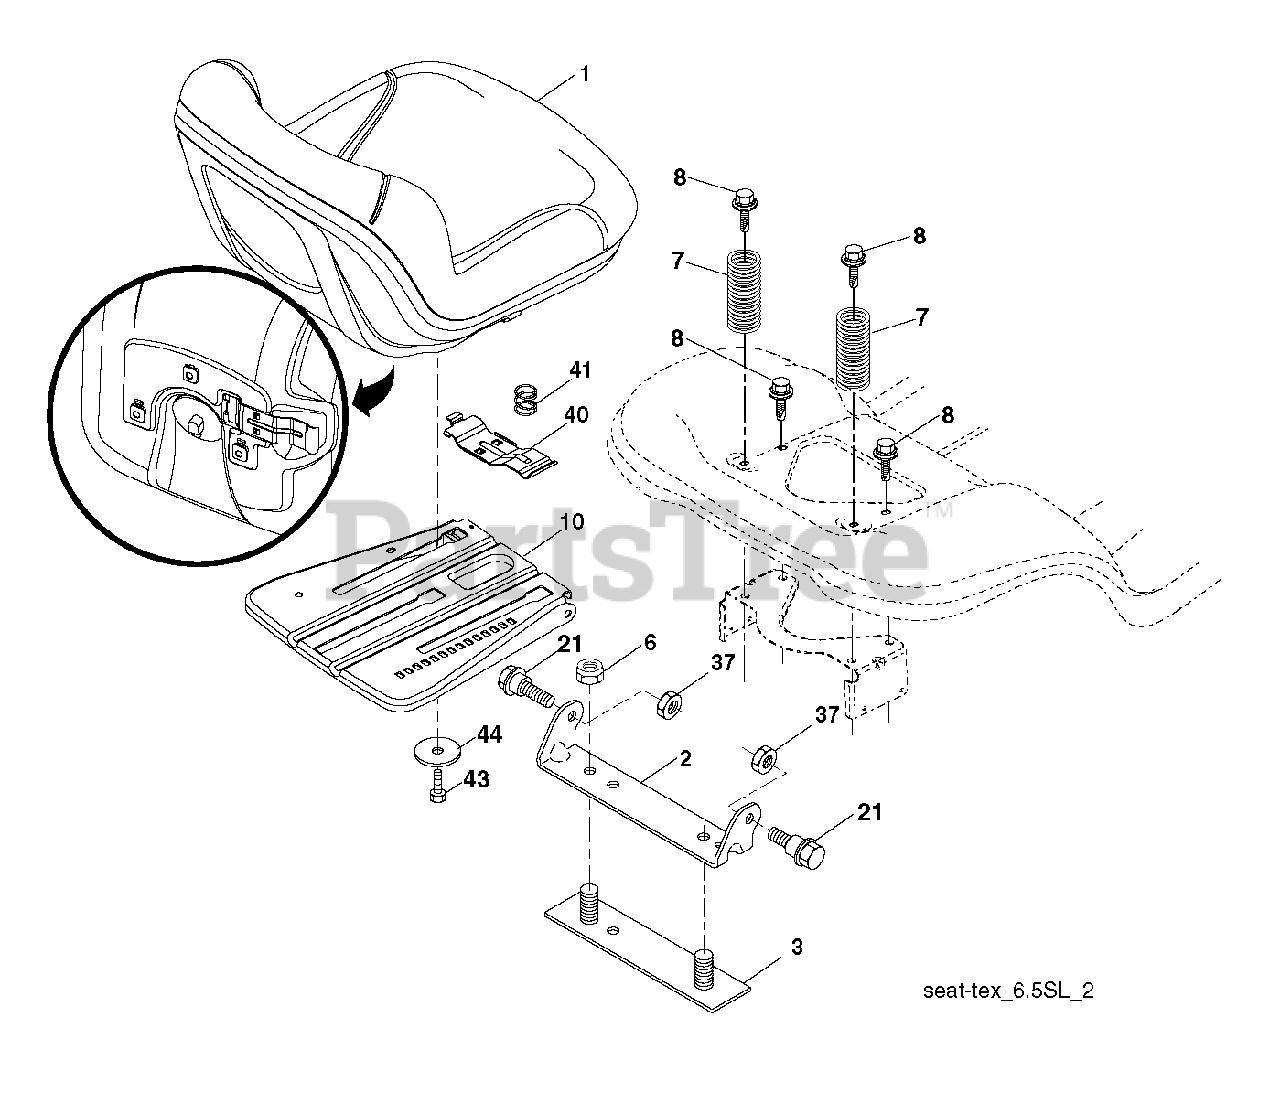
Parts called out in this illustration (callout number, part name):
1	SEAT.TH150.MS498.GRY.HUSQ.TEX
2	BRKT.PIVOT.FENDER
3	STRAP
6	NUT
7	SPRING COMPRESSION
8	BOLT, 5/16-18 X 1 3/4
10	PAN.ASM.SEAT.3PT
21	BOLT.SHOULDER.5/16-18
37	NUT.71038.31-18.HEX.NYLOCK
40	HANDLE.SLIDE.SEAT.TEX.BLACK
41	SPRING.LATCH.SEAT.TEX
44	WASHER 13/32 X 2-3/8 X 12GA
